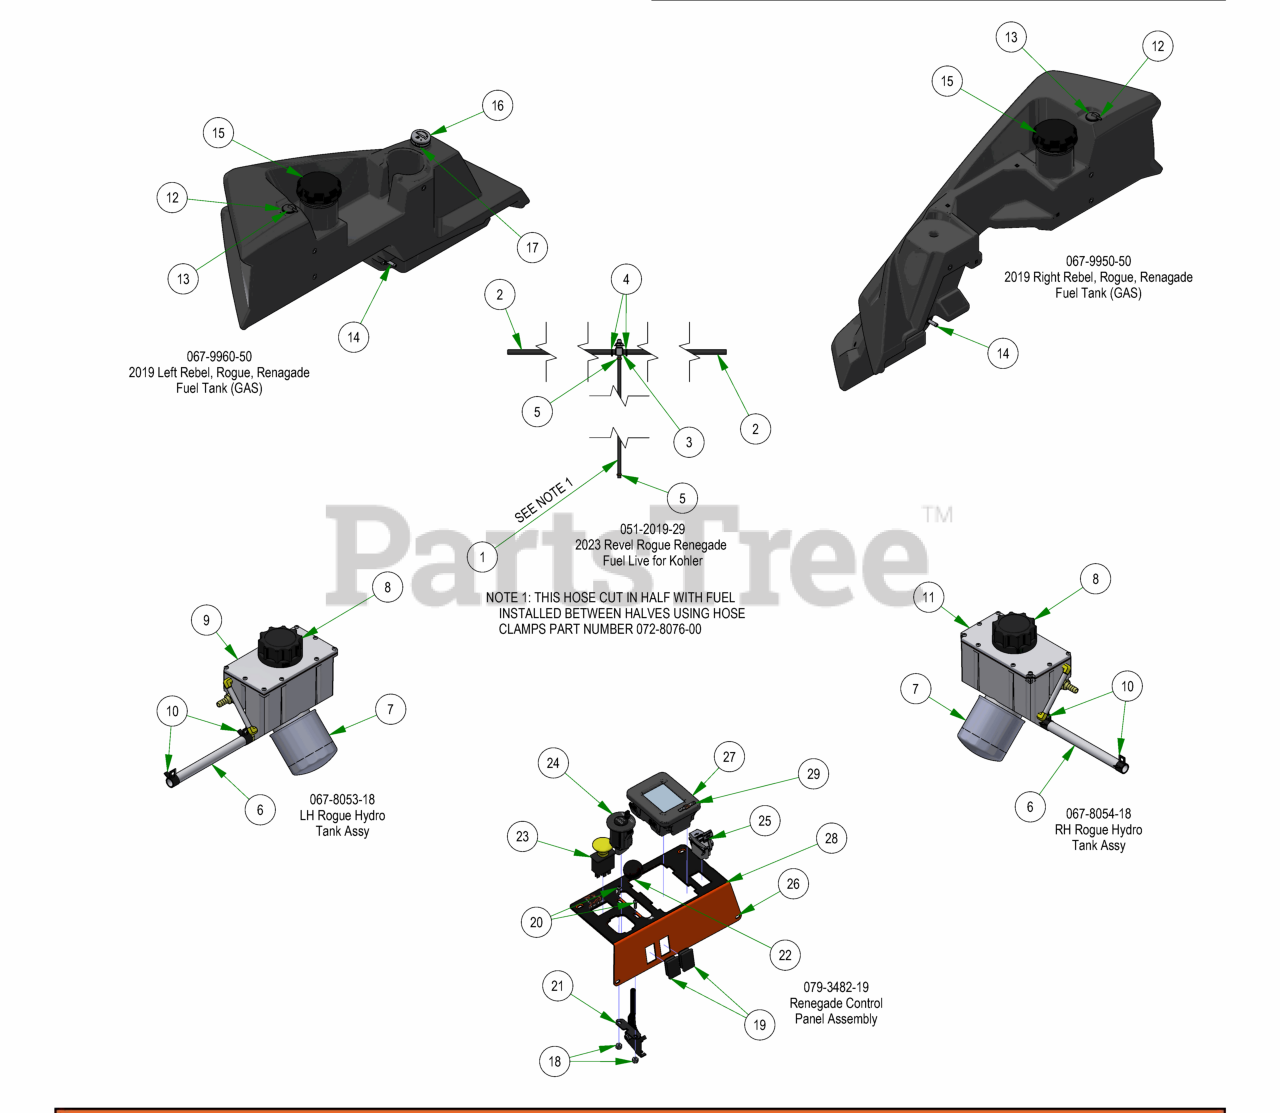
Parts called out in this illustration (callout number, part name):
1	1/4" Fuel Line Hose
2	5/16" fuel line hose
3	3 Way Fuel Shut-Off Valve 5/16 x 5/16 x 1/4
4	5/16 Fuel Line Clamp
5	1/4 Fuel Hose Clamp
6	1/2 Clear Braded Hose Priced/Foot
7	Hydraulic Filter
8	Hydraulic Tank Cap W/Dipstick
9	2019 Left Outlaw Gen2 Hydro Tank Suspension Only
10	1/2 Hose Clamp
11	2019 Right Outlaw Gen2 Hydro Tank Suspension Only
12	Roll Over Valve Grommet
13	Rollover Valve
14	Fuel Pick-up
16	Fuel Gauge with Grommet
17	Fuel Gauge Grommet
18	10-24 Nylon Insert Locknut
19	Light Plug
20	10-24 X 5/8 BS Button Head Bolt
21	Universal Throttle Head - 2012
22	Throttle Knob
23	PTO Switch
24	2019 Push to Start Switch w/fob
26	2019 Outlaw Digital Control Panel
27	2019 LED Display
28	2022 Renegade (Gas) Control Panel Decal
29	2022 Digital Display Decal
